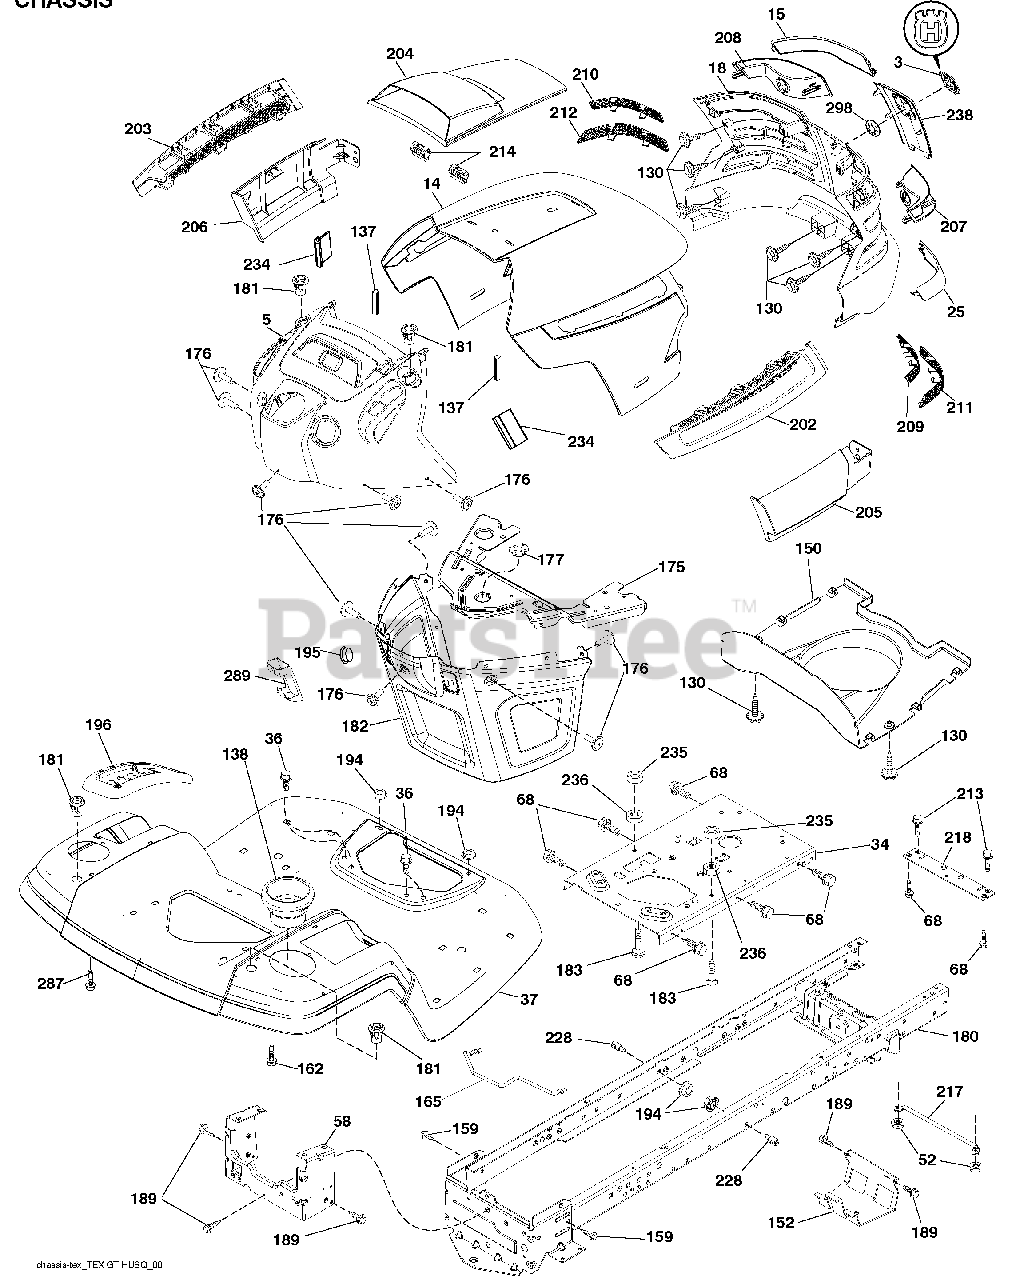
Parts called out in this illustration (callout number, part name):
3	Logo
14	Hood
34	Plate Engine
36	Screw 5/16-18 x 3/4
52	Nut Crown Lock 5/16
58	Drawbar Upper
68	Screw THDROL 5/16-18 x 1/2
130	Screw #10 x 0.750 BOS Thread
137	Bumper Dash
138	Cupholder
152	Shield Browning
159	Screw Hexwash Thor 3/8-16 x 3/4
165	Support Tank Rear
175	Crossmember Plate
176	Screw 10-24 x 5/8
177	Bushing Steering
181	Bushing Mtg. Fender Crgo
182	Dash Lower
183	Bolt 5/16-18 x 1-1/4 Full Thd
189	Screw 5/16-18 x 3/4
194	Nut Lock Hex Flange 5/16-18
196	Console Asm. Deck Lift
202	Vent Side Hood RH
203	Vent Side Hood LH
204	Vent Top Hood
205	Skirt Side RH
206	Skirt Side LH
209	Insert Hex Top RH
210	Insert Hex Top LH
211	Insert Hex Bottom RH
212	Insert Hex Bottom LH
213	Bolt 5/16-18 x 3/4
214	Clip Retainer
217	Rod Pivot Hood
218	X-Piece Hood Stop
228	Stud Fastener
234	Bumper Hood
235	Spacer Fender
236	Nut Lock 5/16-18 unc
287	Screw Hex Washead 1/4-20 x 3/8
289	Plug Cruise/Phone
